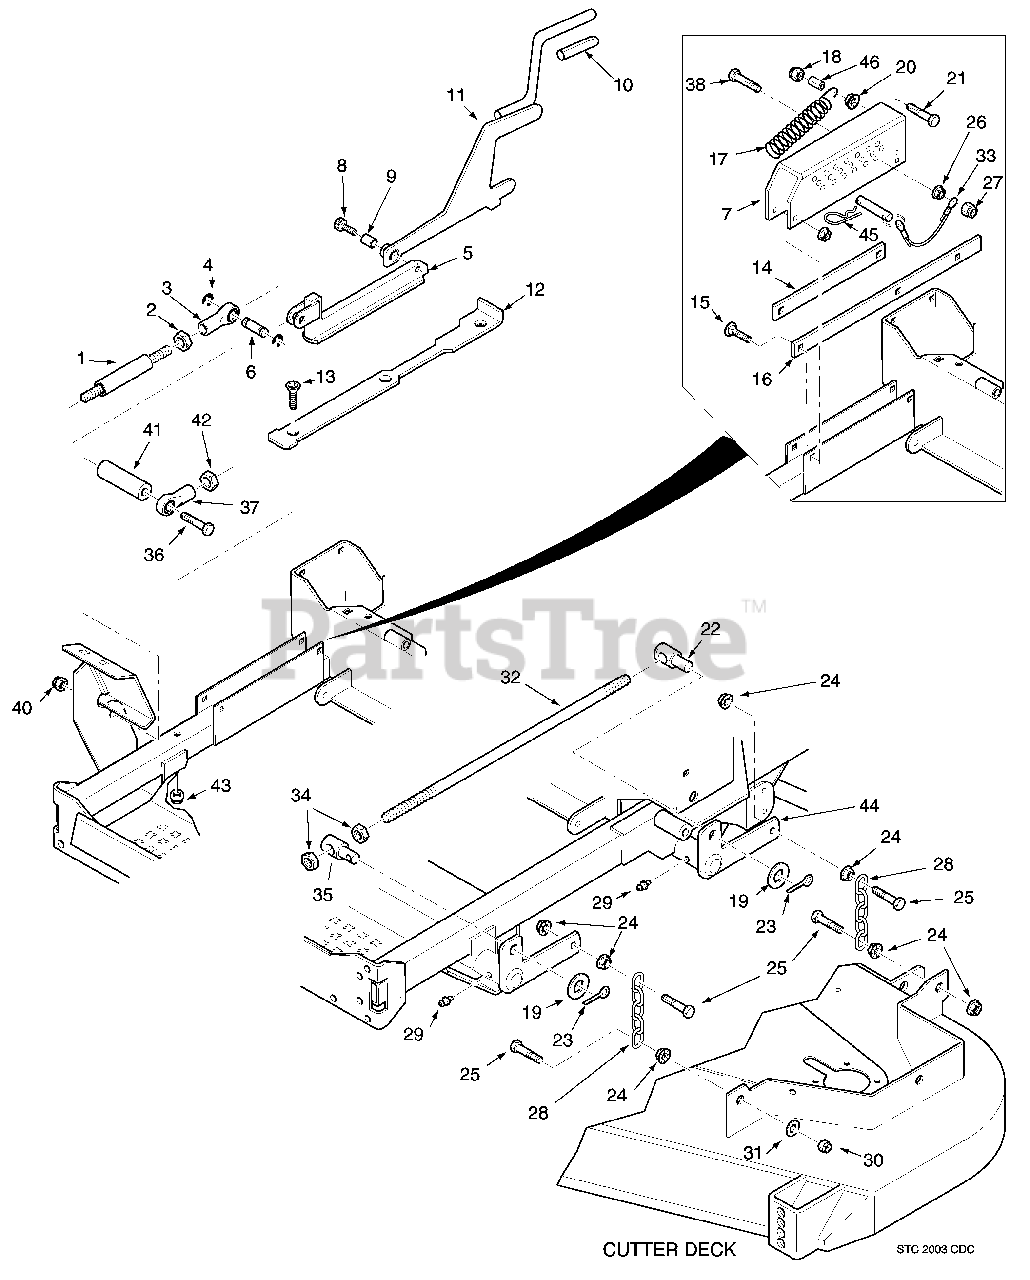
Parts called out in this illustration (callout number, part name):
1	Rod, Deck Lift Linkage
2	Nut, Jam 1/2-20 LH Thread
3	Rod End, 1/2-20 Female Thread
4	Retaining Ring, 1/2" External "E"
5	Slide, Deck Height Adjust
6	Pin, Deck Lift
7	Bracket, Cutting Height Adjustment
8	Bolt, Shoulder 1/2-3/4"
9	Bushing .502 ID
10	Grip, Deck Latch Lever
11	Lever, Deck Latch
12	Slide, Cutting Height
13	Screw, Cap 5/16-18 x 3" FHHS
14	Guide, Short
15	Bolt, Carriage 5/16-18 x 1"
16	Guide, Long
17	Spring, Helper
18	Nut, 3/8-16 Center Lock
19	Flatwasher, 5/8-.656 x 1.312 x .095
20	Nut, 3/8-16 Serr. Flange
21	Bolt, Hex Head 3/8-16 x 1-1/4"
22	Swivel Joint LH
23	Cotter Pin, 3/16 x 1"
24	Nut, Serr. Flange 3/8-16
25	Bolt, Hex Head 3/8-16 x 1-1/2"
26	Nut, Serr. Flange 3/8-16
27	Nut, Elastic Stop 3/8-16
28	Chain
29	Grease Fitting, 1/4-28 Self Tap
30	Nut, Elastic Stop 3/8-16
31	Flatwasher, 3/8-.391 x .938 x .105
32	Stud, 1/2-13 x 20"
33	Lanyard Pin
34	Nut, 5/8-11 UNC
35	Swivel Joint RH
36	Bolt, Hex Head 1/2-13 x 5"
37	Rod End, 1/2-20 Female RH Thread
38	Bolt, Hex Head 3/8-16 x 3-1/2"
39	Spacer
40	Lock Nut, 1/4-20
41	Spacer
42	Nut, 1/2-20 UNF-2B
43	Nut, Elastic Stop 5/16-18
44	Lift Bellcrank Weldment, LH Rear
45	Hair Pin Cotter, .177 x 3-1/4"
